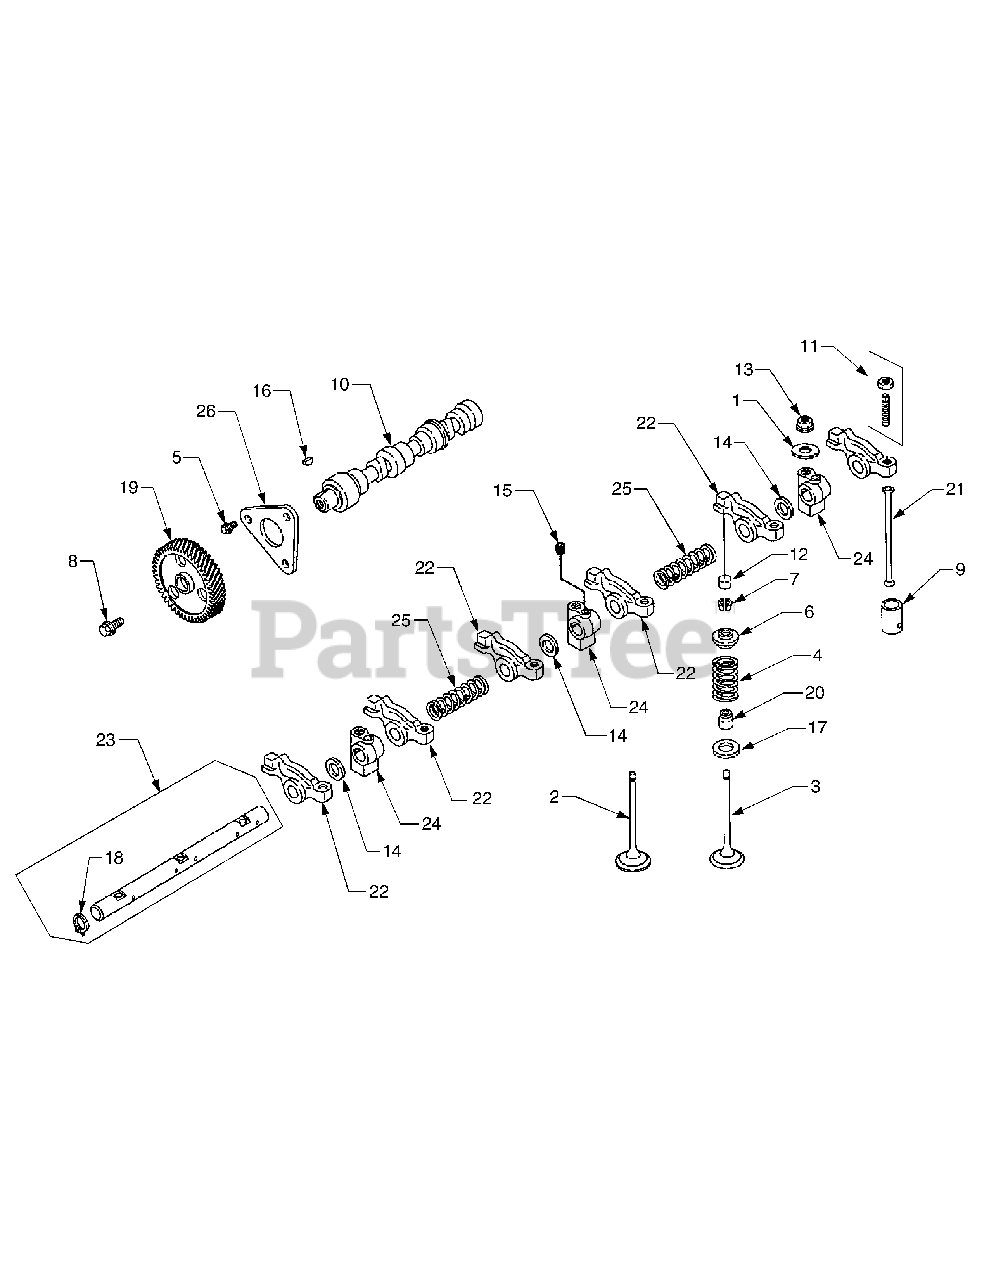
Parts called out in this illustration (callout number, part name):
1	Washer, Flat
2	Valve, Exhaust
3	Valve, Intake
4	Spring, Valve
5	Screw, Hex, 6mm
6	Retainer, Valve
7	Keeper, Valve, Set of 2
8	Screw, Metric
9	Tappet, Valve
11	Adjuster, Rocker Arm
12	Cap, Valve
13	Nut, Hex Metric
14	Washer, Spacer
15	Screw, Metric
16	Key, Timing
17	Seat, Valve Spring
20	Seal, Valve
22	Arm, Rocker
23	Shaft, Rocker Arm
24	Support, Rocker Arm
25	Spring, Rocker Shaft
26	Retainer, Camshaft
